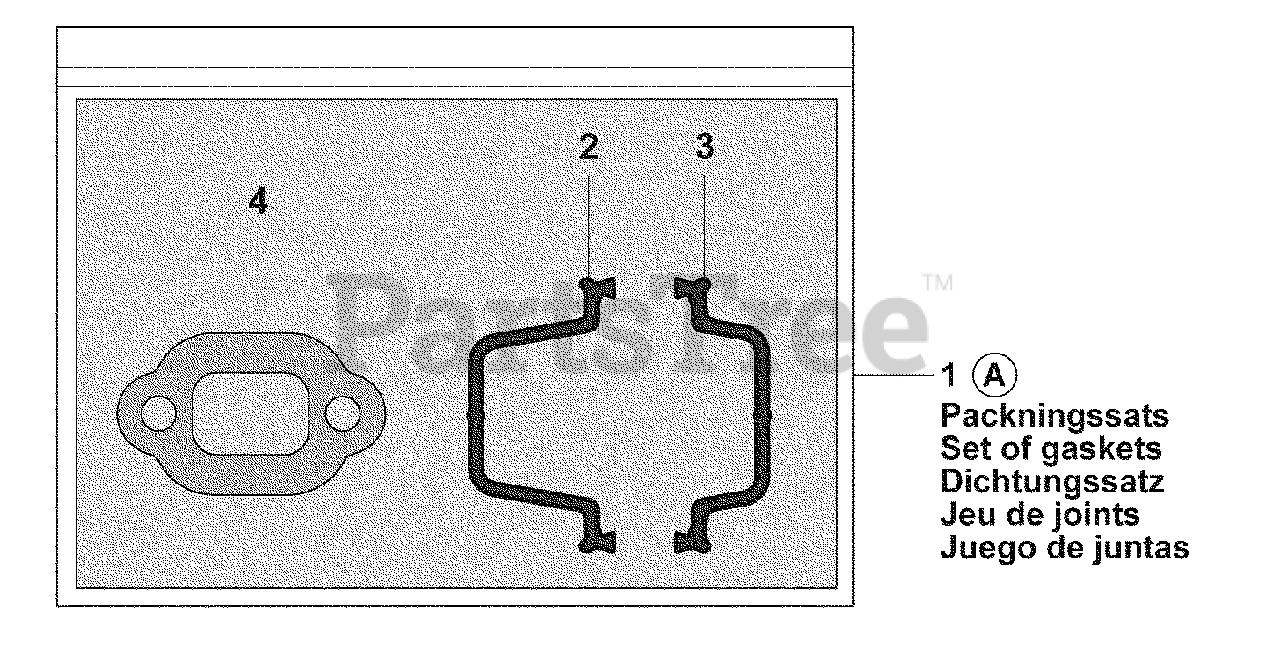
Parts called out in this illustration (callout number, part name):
1	Gasket Set
2	Cylinder Gasket, Front
3	Cylinder Gasket, Rear
4	Gasket
